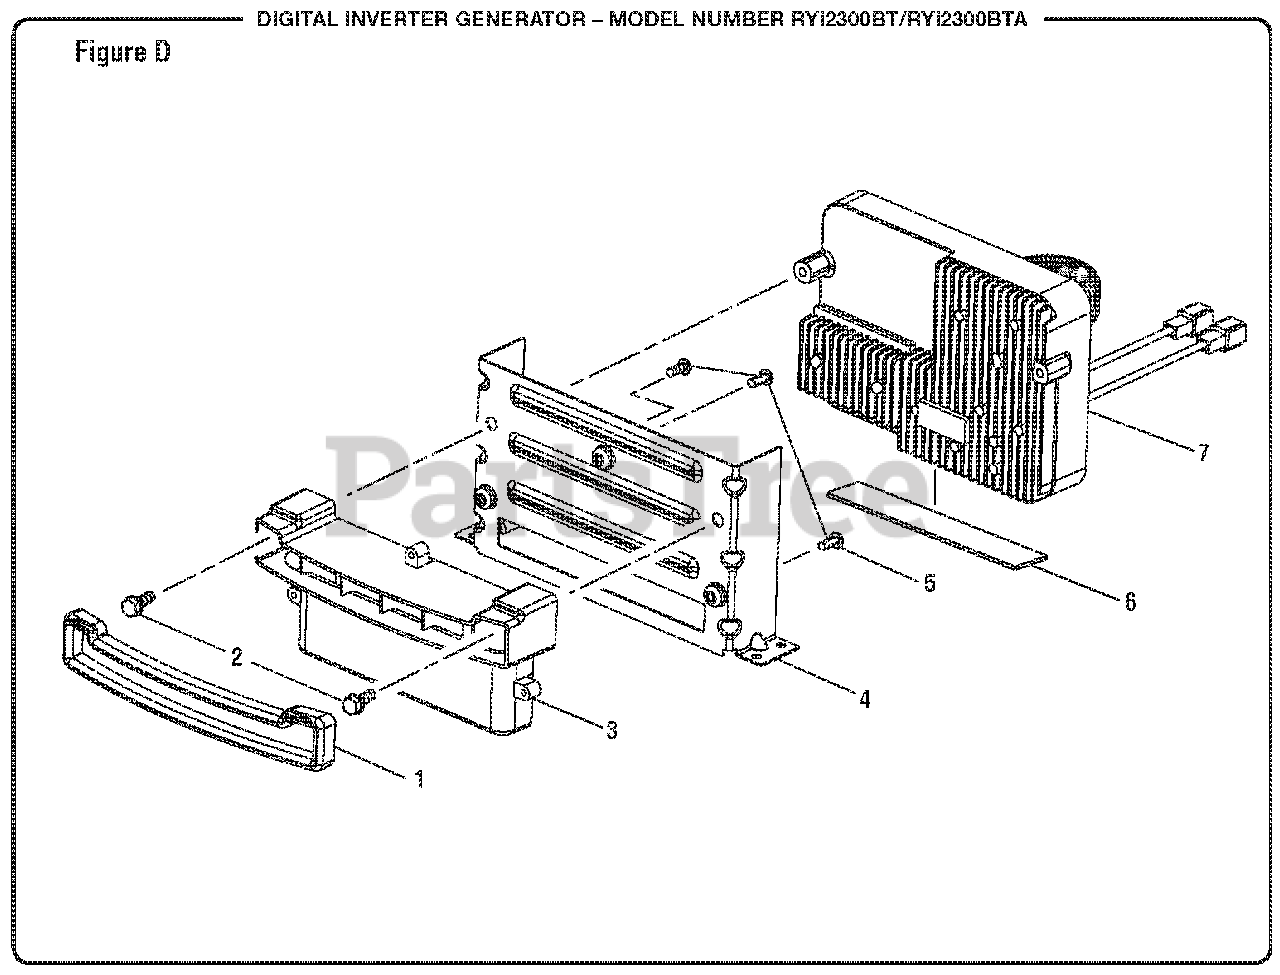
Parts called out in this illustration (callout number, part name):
1	Rubber Trim
2	Bolt (M6 x 12 mm, Hex Hd.)
3	Baffle (Engine Intake)
5	Screw w/Washer (M4 x 10 mm, T20 Torx Hd.)
6	Rubber Pad
7	Inverter Module
